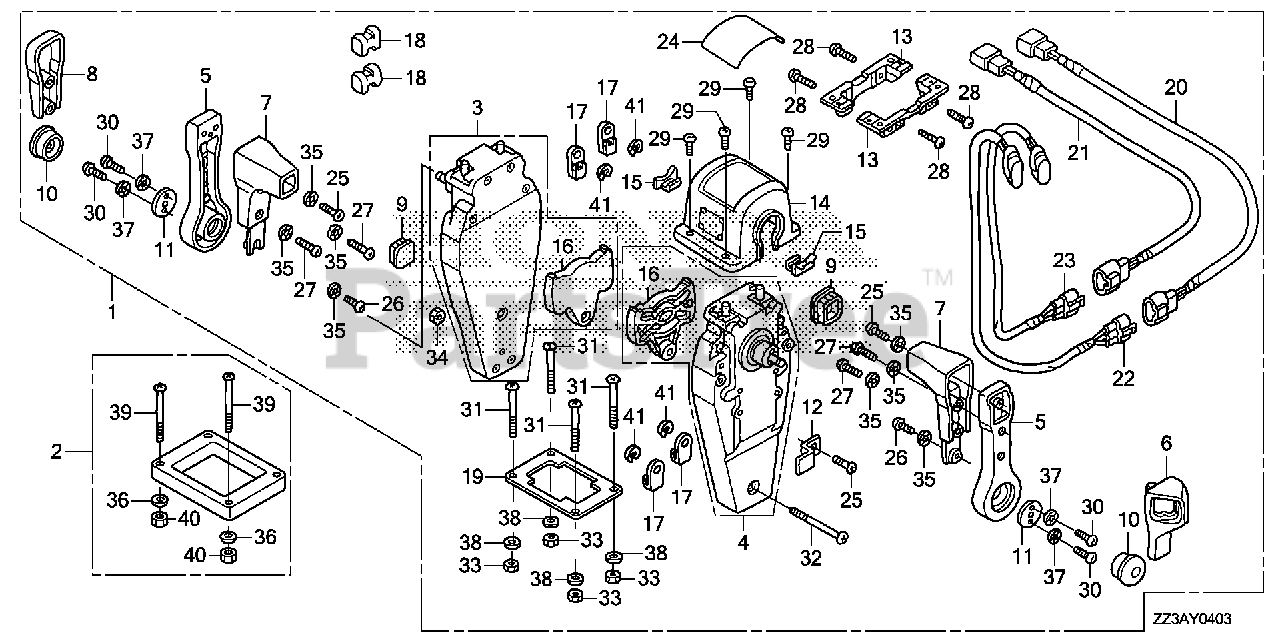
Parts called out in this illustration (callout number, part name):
1	BOX KIT, REMOTE CONTROL (TOP MOUNT DUAL)(L)
2	SPACER KIT, REMOTE CONTROL BOX (TOP MOUNT DUAL)
3	HOUSING ASSY., L. (INNER) (TOP MOUNT)
4	HOUSING ASSY., R. (INNER) (TOP MOUNT)
5	HANDLE, REMOTE CONTROL
6	COVER, R. GRIP
7	GRIP, REMOTE CONTROL HANDLE
8	COVER, DUAL GRIP
9	CAP, GRIP
10	BUTTON, THROTTLE
11	PLATE, HANDLE
12	PLATE, CABLE CLAMP
13	BRACKET, REMOTE CONTROL HOUSING
14	HOUSING, DUAL REMOTE CONTROL BOX
15	HOUSING, LEAD
16	PLATE, DWELL
17	TERMINAL, CABLE
18	SPACER, CABLE CLAMP
19	GASKET, DUAL
20	SUB-HARNESS ASSY., POWER TRIM-TILT (A)
21	SUB-HARNESS ASSY., POWER TRIM-TILT (B)
22	SWITCH ASSY., POWER TRIM-TILT (A)
23	SWITCH ASSY., POWER TRIM-TILT (B)
24	MARK, REMOTE CONTROL (DUAL)
25	SCREW, PAN (5X16)
26	SCREW, PAN (5X10)
27	SCREW, PAN (5X20)
28	SCREW, PAN (5X18)
29	SCREW, PAN (4X10)
30	SCREW, PAN (6X18)
31	SCREW, PAN (5X40)
32	SCREW, PAN (5X55)
33	NUT, HEX. (5MM)
34	NUT, HEX. (5MM)
35	WASHER, LOCK (5MM)
36	WASHER, PLAIN (5MM)
37	WASHER, LOCK (6MM)
38	WASHER, PLAIN (5MM)
39	SCREW, PAN (5X65)
40	NUT, HEX. (5MM)
41	E-RING (6MM)
